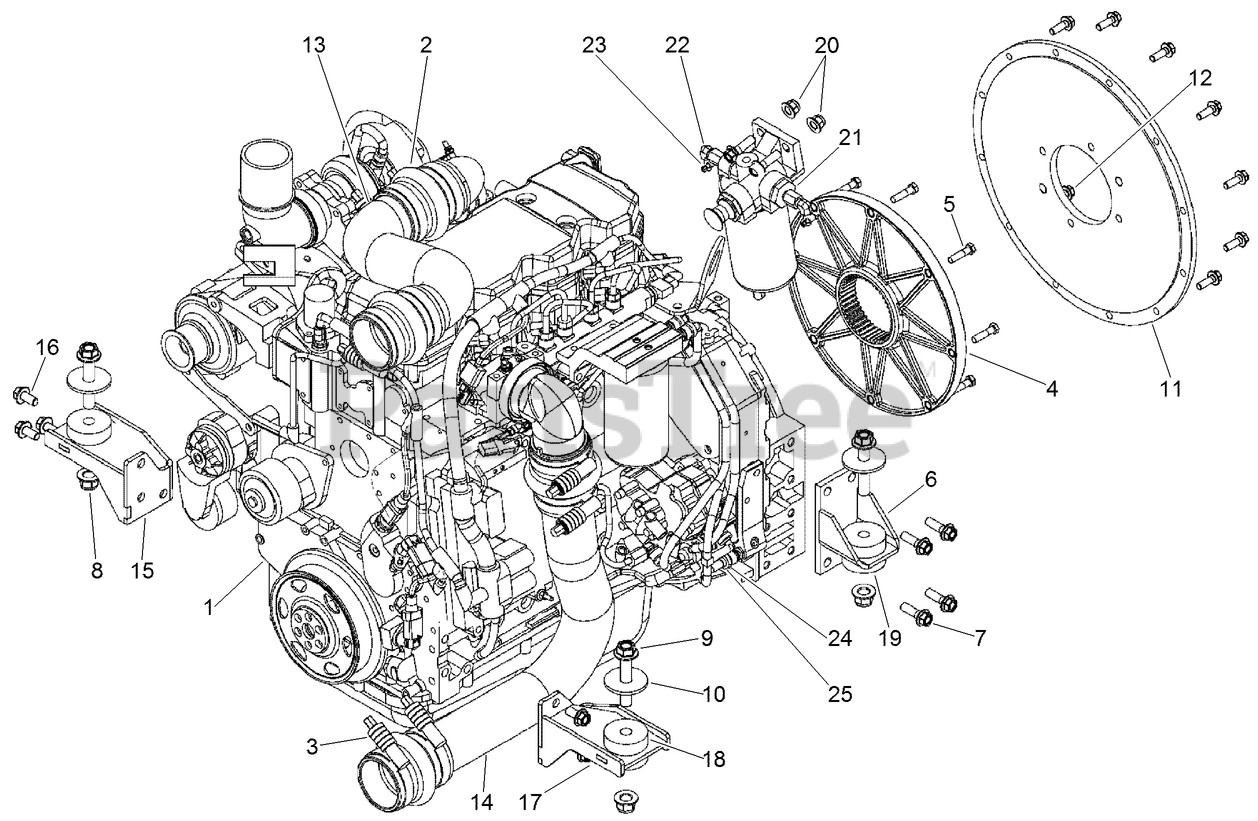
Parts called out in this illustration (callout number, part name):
1	ENGINE - 121 HP Cummins
2	ADAPTER-HUMP
3	CLAMP-TORQUE, CONSTANT
4	COUPLING-DRIVE, NYLON
5	BOLT-hex, 3/8 NC x 1-1/2 inch
6	MOUNT - Motor, Rear
8	NUT-HHF
9	SCREW-FLANGE
11	PLATE-MOUNTING, PUMP
12	SCREW-HH
13	PIPE - Charge Air
14	PIPE - Charge Air
15	WELDMENT - Engine Mount, LH Front
16	SCREW-HHF
17	WELDMENT - Engine Mount, RH Front
18	MOUNT - Engine, Yellow Dot
19	ISOLATOR-WEAR PLATE, GREEN
20	NUT-HHF, LOCK
21	FITTING-REDUCER
22	ELBOW - 90 Hose Stem, 3/8 ID x 174 NPTF
23	CLAMP-Hose Type M #04
24	SEAL-FITTING, FUEL
25	FITTING, FUEL HOSE BARB - M12 x 3/4 Hose ID
